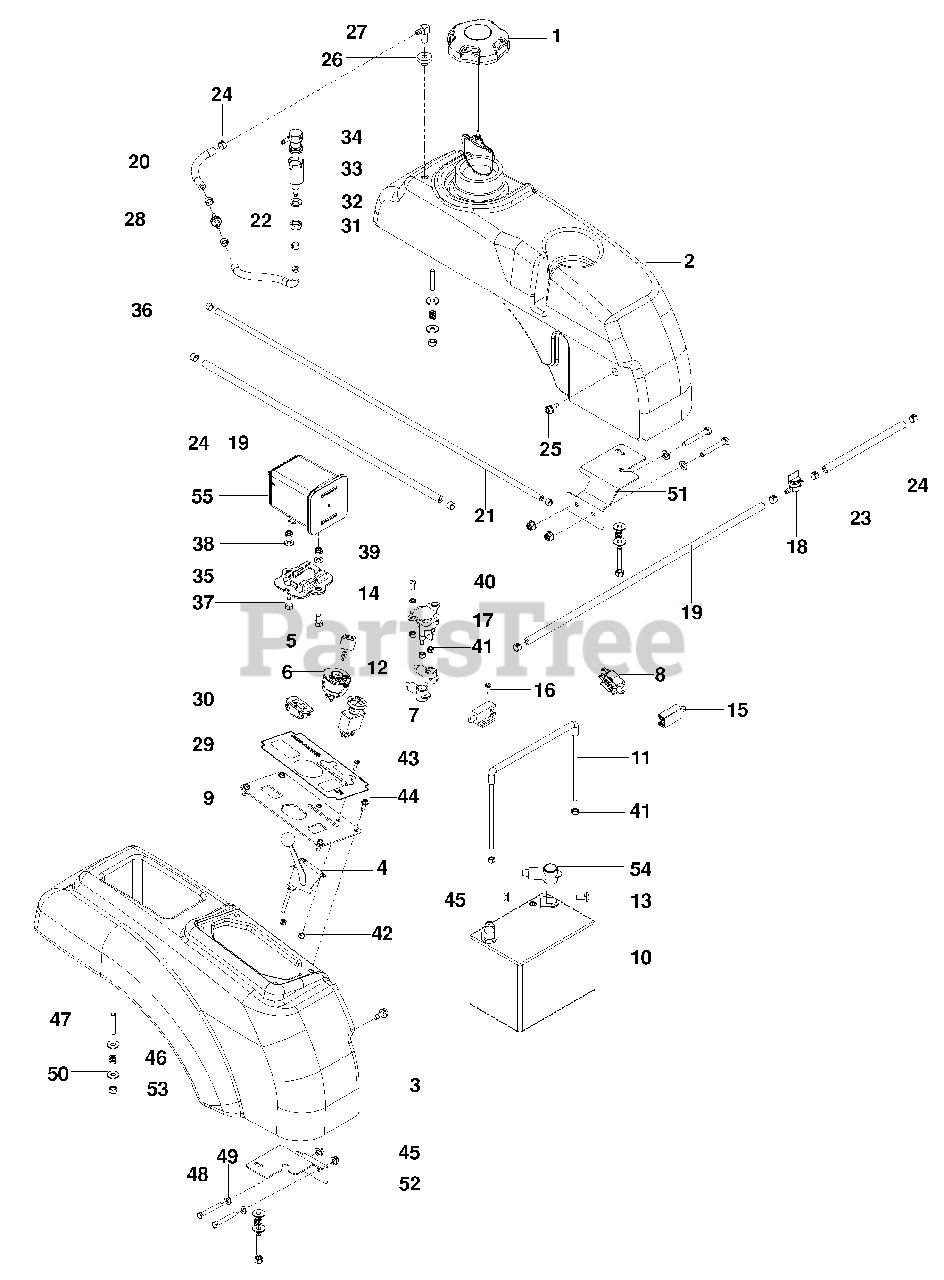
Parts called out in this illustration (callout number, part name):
1	CAP, FUEL
2	TANK ASSY, LT
3	CONSOLE, RT
4	CABLE, THROTTLE
5	KEY, IGNITION
6	SWITCH, IGNITION
7	SWITCH, CLUTCH
8	SWITCH, BRAKE
9	PANEL, CONTROL
10	BATTERY
11	TIE DOWN, BATTERY
12	TERMINAL COVER
13	RHSNB 5/16-18 x 3/4
14	WASHER 1/4 ITLW
15	SWITCH, NC
16	SCREW 10-24 x 5/8 WSH HD
18	FUEL VALVE
19	FUEL LINE 24"
20	FUEL LINE 5"
21	FUEL LINE 33"
22	FUEL LINE 7"
23	FUEL LINE 8"
24	HOSE CLAMP
25	BOLT 5/16-18 x 3/4 THD FRM
26	GROMMET, RUBBER
28	VALVE, ANTI-SLOSH
29	DECAL, CONTROL PANEL
30	HOUR METER
31	NUT 1/2-13 HEX JAM
32	WASHER 1/2 SLW
33	BODY, ROLLOVER VALVE
34	VALVE, ROLLOVER
35	BRACKET, CANISTER
36	CLAMP, HOSE
37	HCS 5/16-18 x 5/8
38	WASHER 5/16 SAE FLAT
39	NUT 5/16-18 HEX NYL INSERT
40	SCREW 1/4-20 x 5/8 BTN SKT
41	NUT 1/4-20 HEX NYLOC
42	NUT 10-24 HEX NYLOC
43	SCREW 10-24 x 5/8 MACHINE
44	SCREW 1/4-20 x 5/8 SLF TAP
45	NUT 5/16-18 FLANGE NYLOC
48	HCS 5/16-18 x 2 1/4
49	WASHER 5/16 SAE FLT
50	WASHER 5/16 STD FLT
51	SUPPORT, TANK LT BLK
52	SUPPORT, TANK RT BLK
53	NUT 5/16-18 HEX NYLOC
55	CANISTER, CARBON
